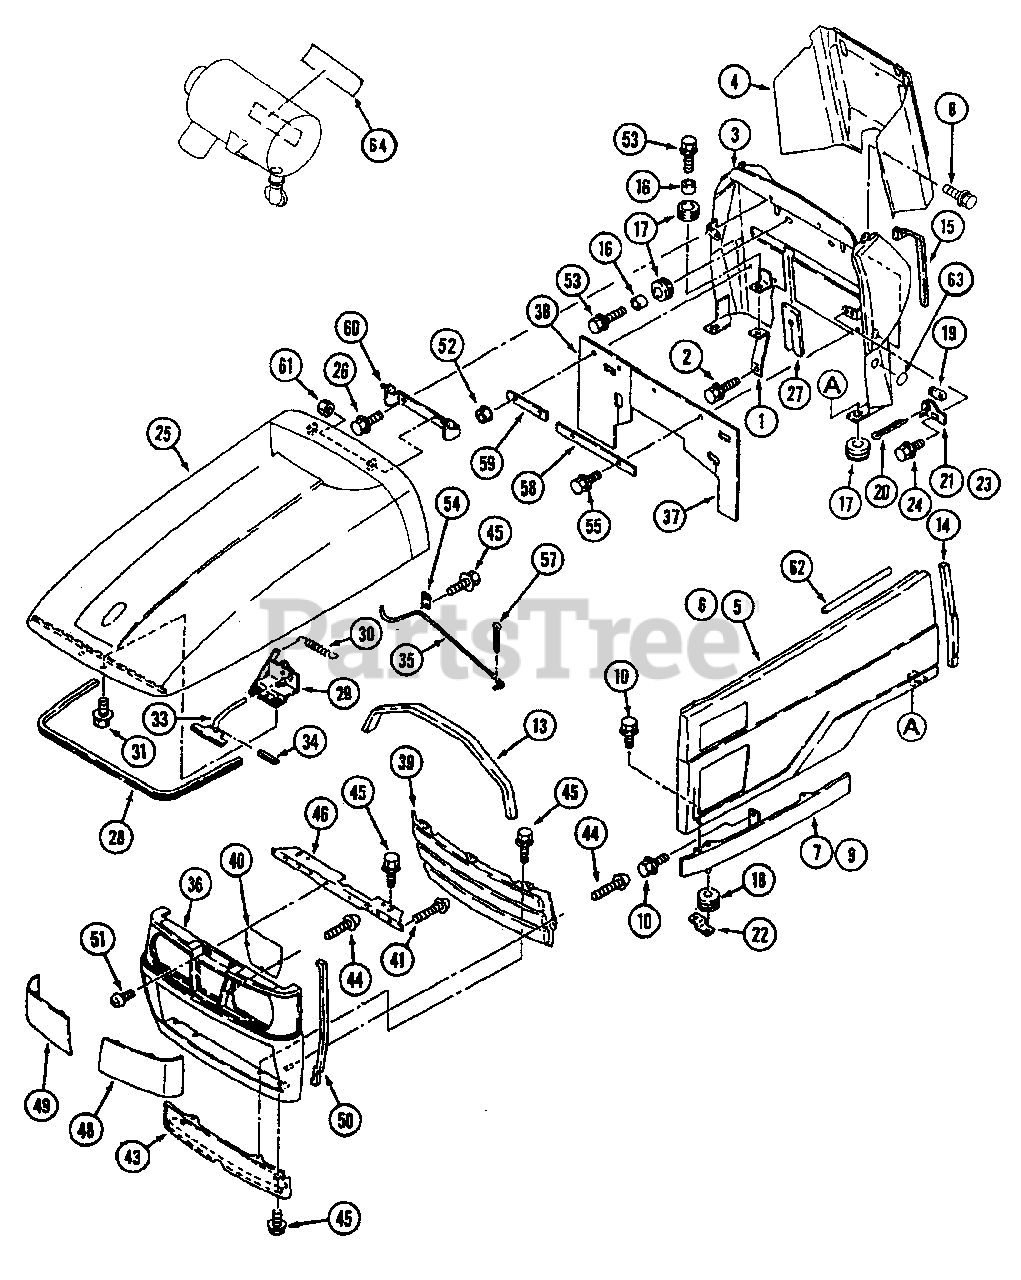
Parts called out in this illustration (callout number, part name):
4	Cover, Panel Rear
5	Cover, Side L.H.
6	Cover, Side R.H.
7	Cover, Side L.H.
8	Bolt
9	Cover,Side R.H.
15	Cushion
29	Bracket, Lever
41	Screw, Tapping
46	Support, Grille
48	Cover, Lamp L.H.
49	Cover, Lamp R.H.
57	Pin,Split
60	Bracket, Hood
62	Rubber, Cushion
